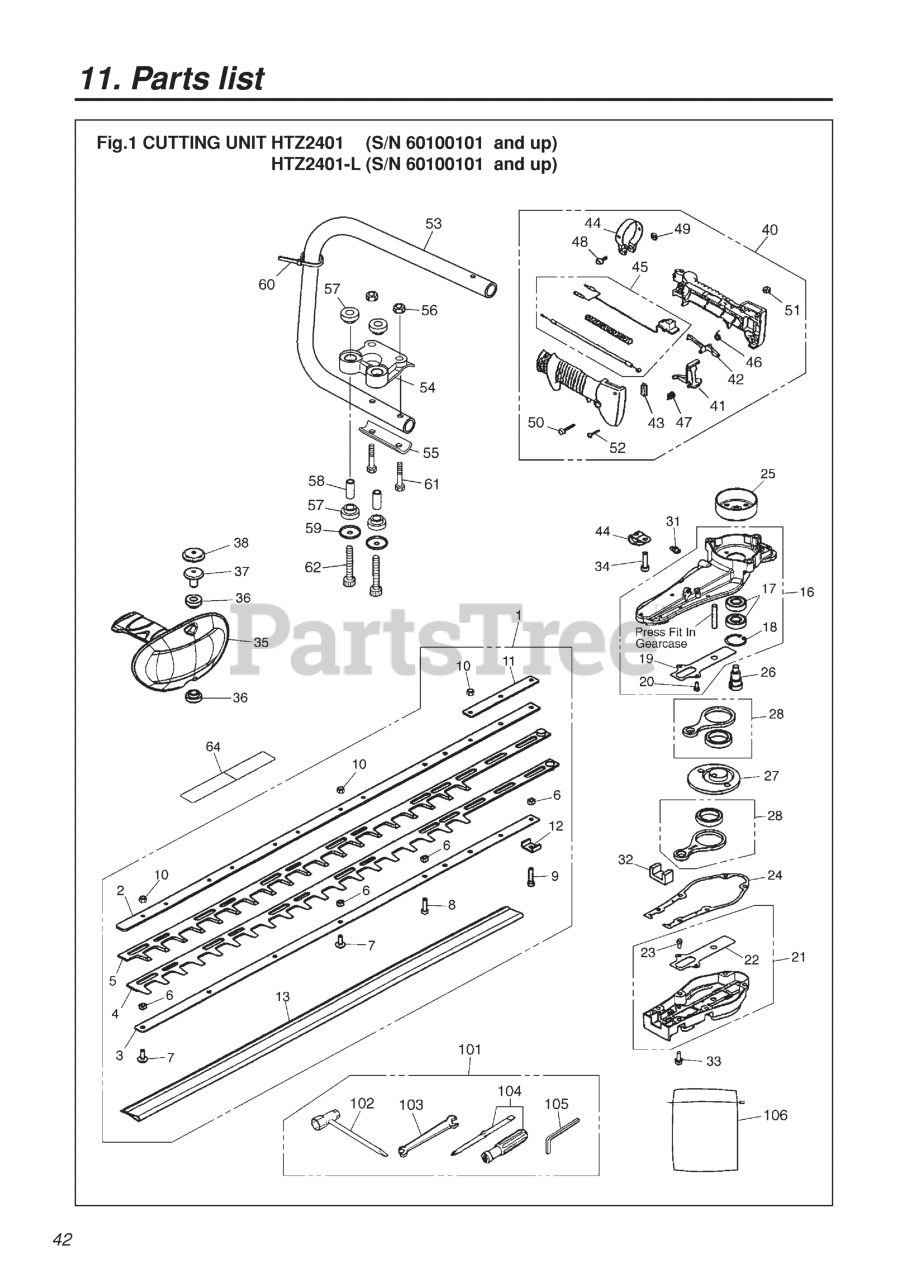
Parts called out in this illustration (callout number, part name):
1	BLADE ASSY
2	PLATE.UPPER
3	PLATE, LOWER
4	BLADE,LOWER
5	BLADE,UPPER
6	SPACER
7	SCREW, BLADE
8	BOLT, M5 X 20
9	BOLT
10	NUT
11	PLATE
12	BRACKET (RPLS T4543-11510)
13	COVER,BLADE
16	GEARCASE-C (RPLS. -6111)
17	BEARING
18	RING, SNAP, M28 x 1.2
20	BOLT
21	CASE-BOTTOM-A
23	BOLT
24	GASKET
26	GEAR, DRIVE
27	GEAR, DRIVEN
28	ROD-A
31	FITTING, GREASE
32	FELT
33	BOLT
34	BOLT, M6 X 25
35	HANDLE-R-COMP
36	SPACER
37	HOLDER
38	CAP
40	LEVER-ASSY
41	LEVER
42	LEVER
43	TOP
44	BAND
45	CABLE-ASSY
46	SPRING
47	SPRING
49	NUT
50	SCREW
51	NUT
52	SCREW
53	PIPE
54	MOUNT
56	NUT, M5 X 4
57	ABSORBER
58	COLLAR
59	WASHER
61	BOLT, M5 X 30
62	BOLT, M6 x 1.35
101	TOOL-SET
103	SPANNER, 8 X 10 (RPLS 2540- )
104	SCREWDRIVER
105	WRENCH (TOOL)
